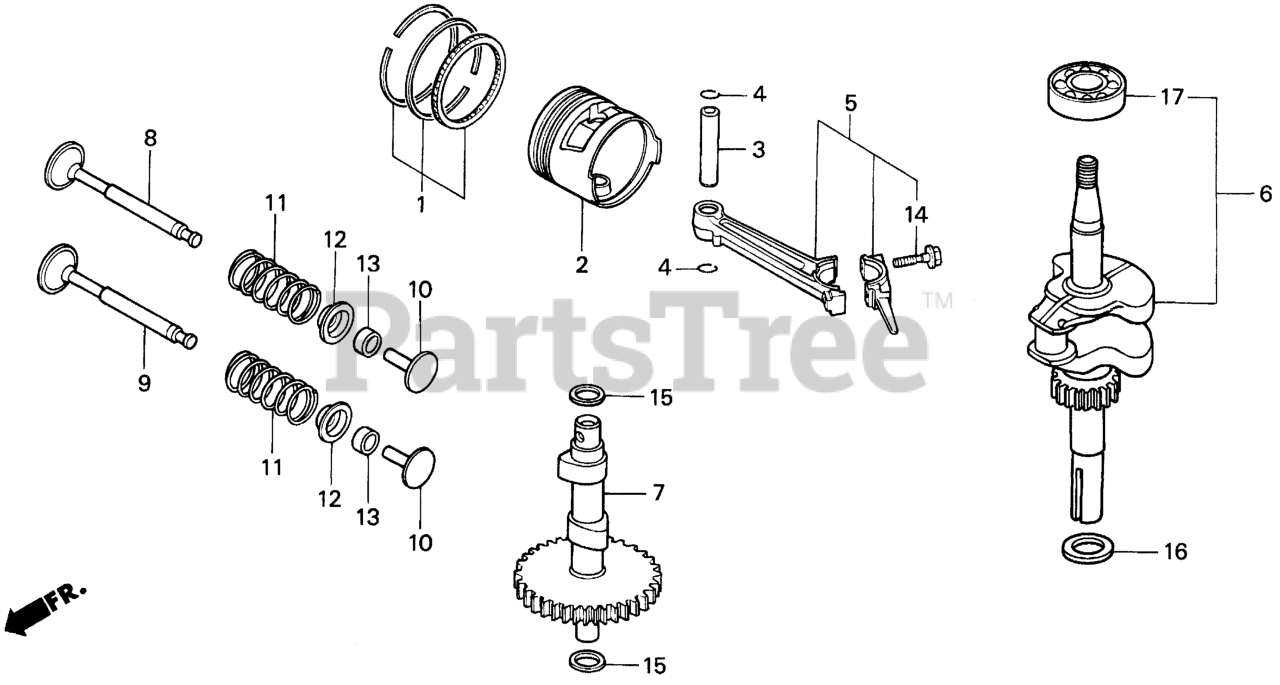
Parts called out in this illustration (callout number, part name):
1	RING SET, PISTON (STD)
1	RING SET, PISTON (OVER SIZE) (0.25)
1	RING SET, PISTON (OVER SIZE)
1	RING SET (OS) (0.50)
1	RING SET, PISTON (0.75)
2	PISTON (STD)
2	PISTON (OVER SIZE) (0.25)
2	PISTON (OVER SIZE) (0.50)
2	PISTON (OVER SIZE) (0.75)
3	PIN, PISTON
4	CLIP, PISTON PIN (10MM)
5	ROD ASSY., CONNECTING (STD)
5	ROD ASSY., CONNECTING (UNDER SIZE) Use up to Engine SN 1214439.
6	CRANKSHAFT
7	CAMSHAFT
8	VALVE, IN.
9	VALVE, EX.
10	LIFTER, VALVE
11	SPRING, VALVE
12	RETAINER, VALVE SPRING
13	ADJUSTER, TAPPET CLEARANCE (3.15)
13	ADJUSTER, TAPPET CLEARANCE (3.25)
13	ADJUSTER, TAPPET CLEARANCE (3.34)
13	ADJUSTER, TAPPET CLEARANCE (3.43)
13	ADJUSTER, TAPPET CLEARANCE (3.52)
13	ADJUSTER, TAPPET CLEARANCE (3.61)
13	ADJUSTER, TAPPET CLEARANCE (3.72)
13	ADJUSTER, TAPPET CLEARANCE (3.82)
14	BOLT, CONNECTING ROD
15	WASHER (12MM)
16	WASHER, THRUST (20X1.00)
17	BEARING, RADIAL BALL (6203)
